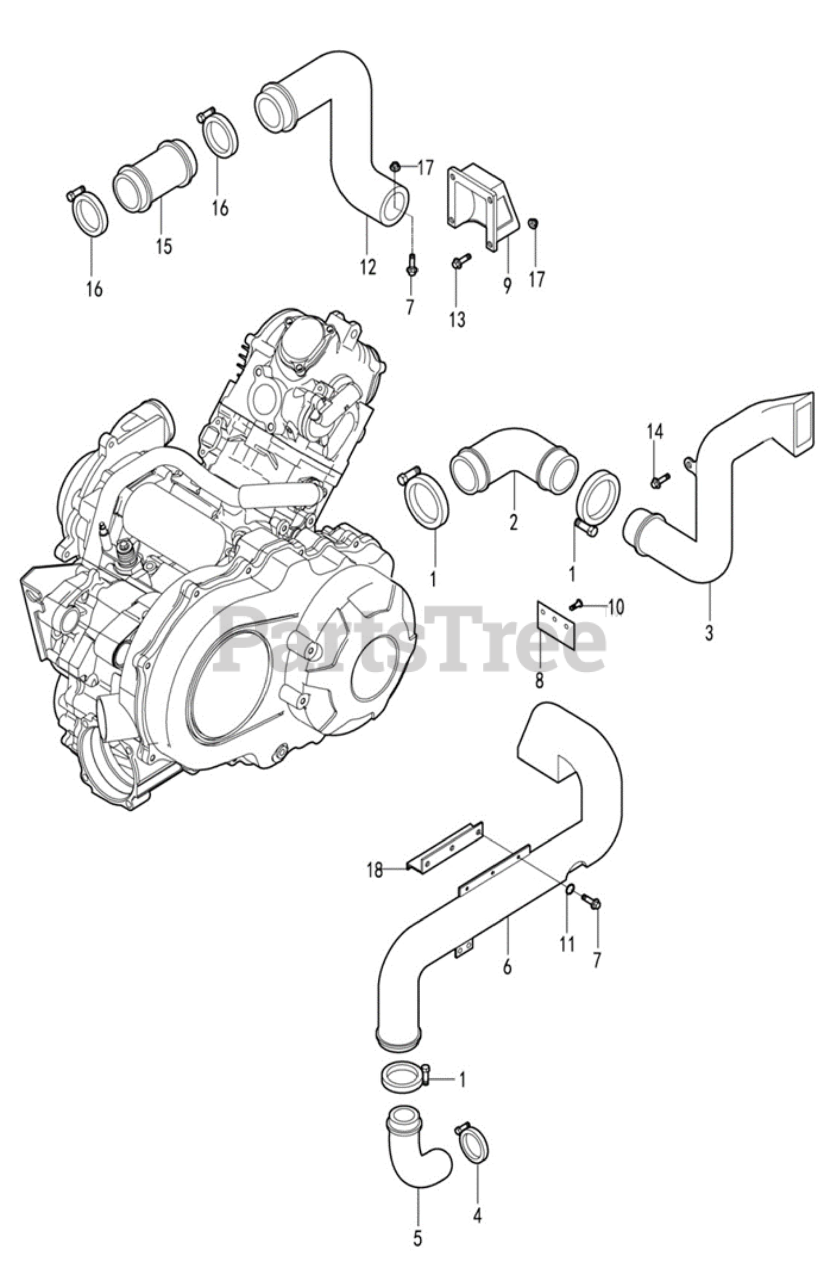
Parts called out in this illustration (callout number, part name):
1	Screw Locking Hoop L
2	Adapter Sleeve I,clutch intake-tube
3	clutch intake-tube
4	Screw Locking Hoop L
5	Adapter Sleeve ,clutch exit pipe
6	outlet Pipe Joint, Clutch
7	Hexagon Flange Bolt M6X16
8	Dustproof Rubber, Clutch Exit Pipe
9	Dust Protection Cover
10	Expansion bolt(Plastic)
11	Flat washer 6
12	Exit Pipe, Fan
13	Cross Large Plate Head Screw M6X12
14	Cross Large Plate Head Screw M6X16
15	Fan Vent Pipe Joint
16	Screw Hoop H
17	Hexagon Flange Nut M6
18	Outlet Pipe Mounting Board, Clutch
